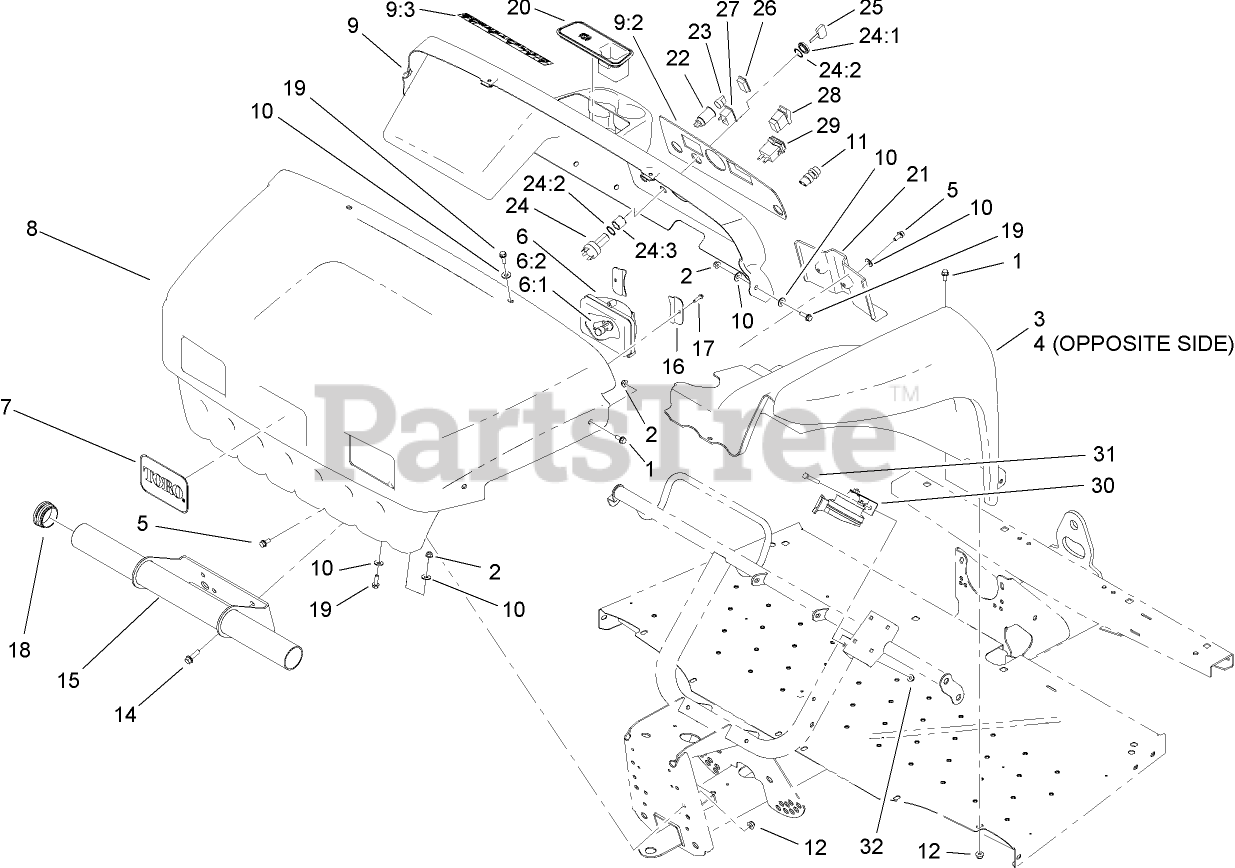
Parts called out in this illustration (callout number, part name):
1	SCREW-HHF
2	NUT-HF, NI
3	LH FENDER ASM
4	RH FENDER ASM
6	HEADLIGHT
6:1	LAMP-12 VOLT
7	DECAL
9	DASH ASM
9:2	DECAL-WARNING
10	WASHER-FLAT
11	BUTTON-HORN
12	NUT-HF, NI
15	BUMPER-TUBE
16	BRACKET-HEADLIGHT
17	SCREW-HWH
18	CAP-END
19	SCREW-HHF
20	PLUG-RUBBER
21	COVER-CHANNEL
22	POINT-POWER
24	SWITCH-IGNITION
24:1	NUT-SWITCH, PLASTIC
24:2	WASHER-LOCK, INTERNAL
24:3	SPACER-SWITCH
25	KEY-IGNITION
26	PLUG-HOLE
27	INDICATOR-LIGHT, LOW-OIL PRESSURE
28	SWITCH
29	HOURMETER
31	SCREW-HH
32	NUT-HF, NI
